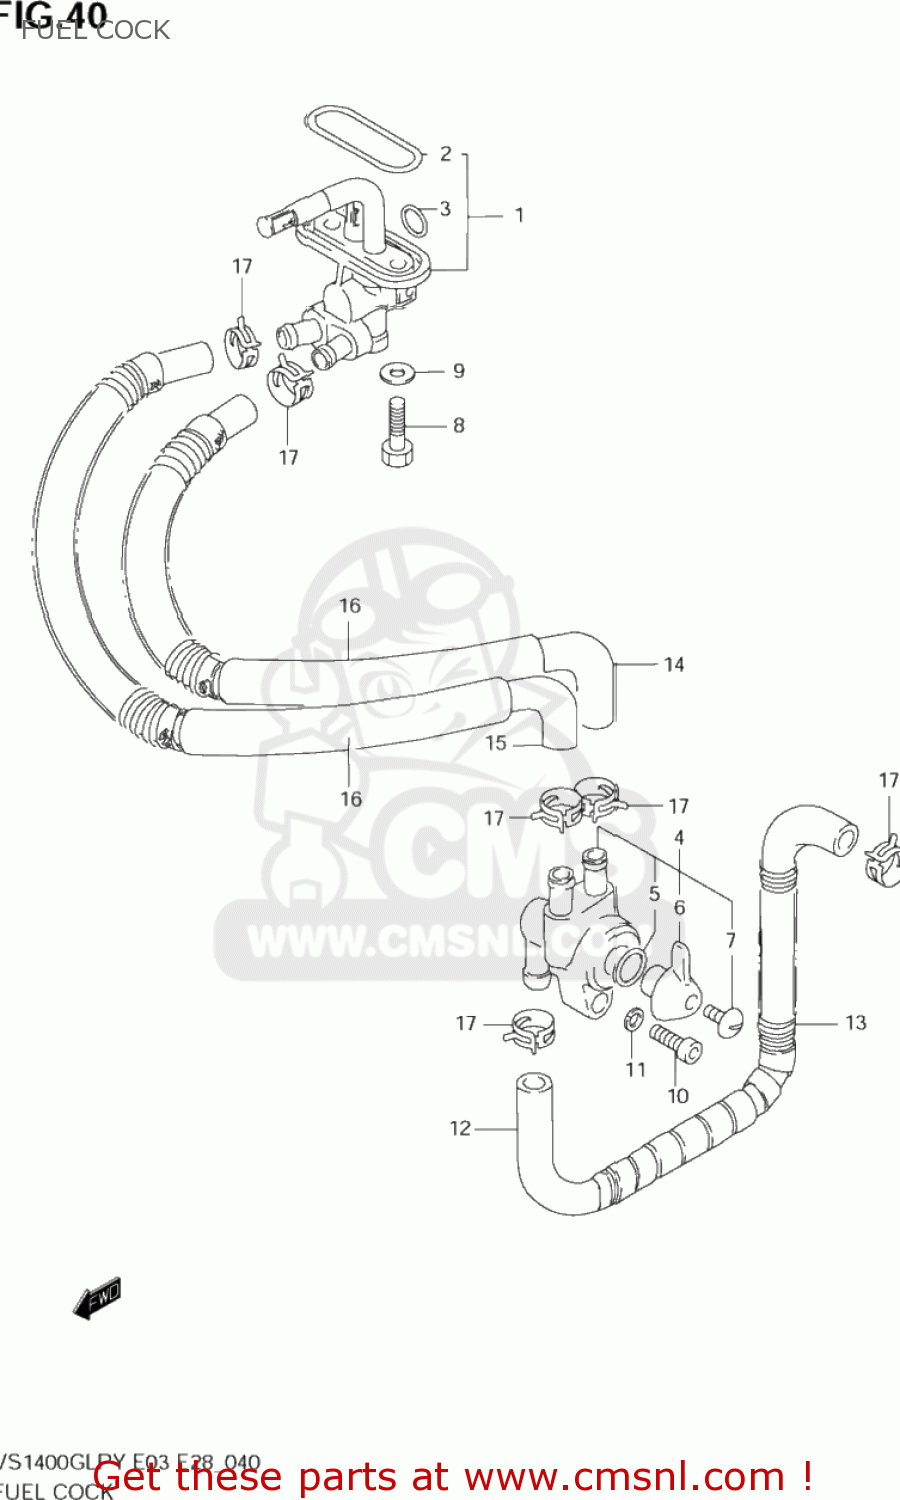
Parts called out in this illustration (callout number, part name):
1	COCK ASSY,FUEL
2	O RING,FUEL COCK
3	O RING,LEVER
4	COCK ASSY,FUEL
5	O RING,LEVER
6	LEVER,FUEL COCK
7	SCREW,COCK LEVER
8	BOLT(6X20)
9	GASKET(6.4X11.5X0.8) (NAS)
10	BOLT
11	LOCK,WASHER
12	HOSE COMP,FUEL PUMP &
13	SPRING
14	HOSE,FUEL
15	HOSE,FUEL NO.2
16	TUBE,FUEL HOSE
17	CLIP
